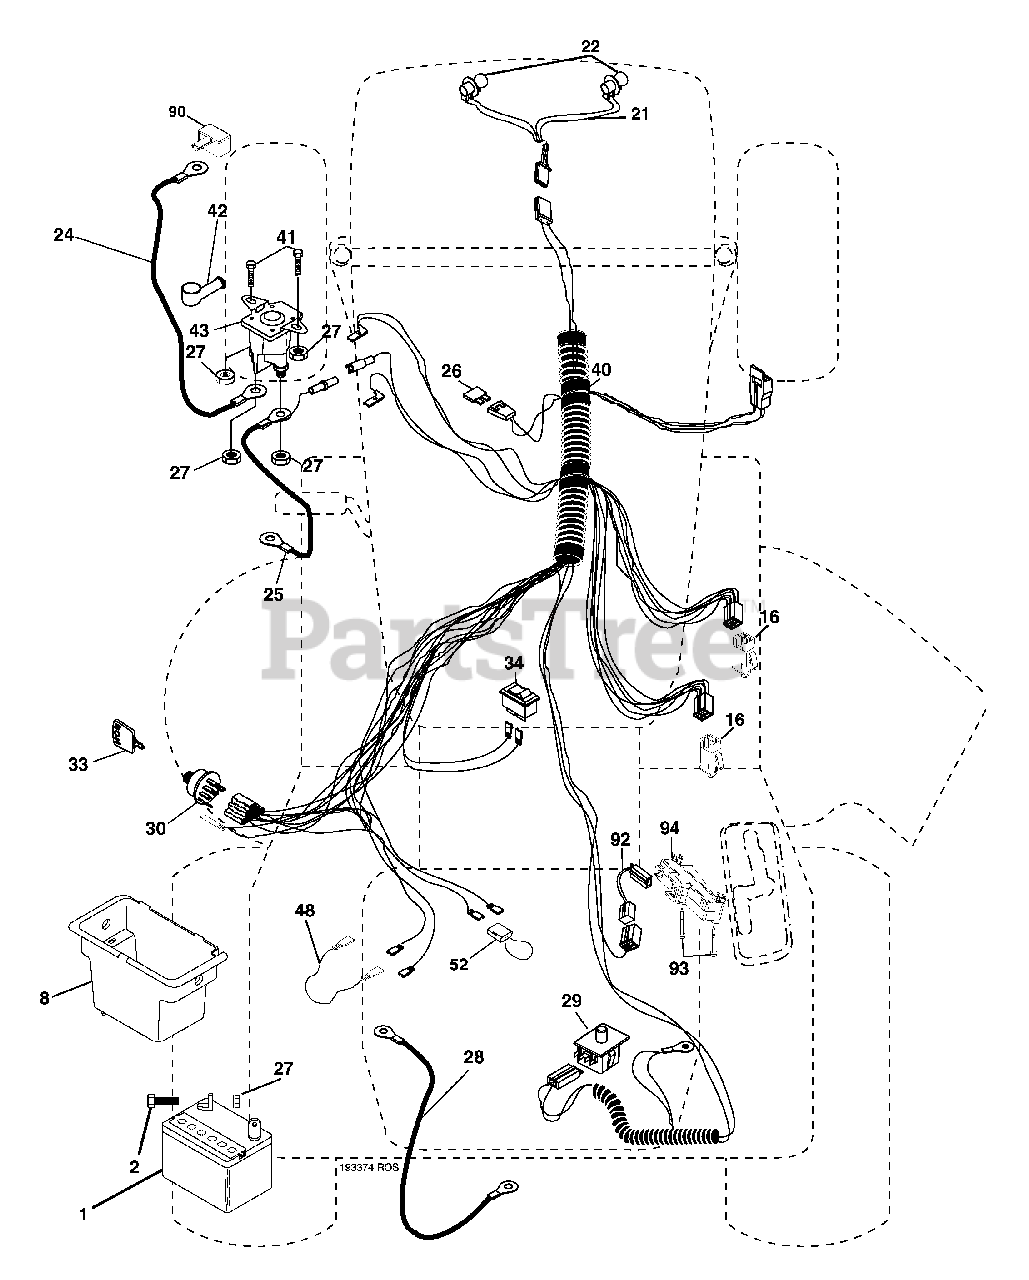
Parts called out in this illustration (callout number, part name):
1	Battery
2	Bolt Hex Hd 1/4-20 unc x 3/4
8	Box Battery
16	Switch Interlock
21	Harness Asm Light W/4152j
22	Bulb Light #1156
24	Cable Battery 6 Ga. 11"red
25	Cable Battery
26	Fuse 20 AMP
27	Nut Keps Hex 1/4-20 unc
28	Cable Ground 6 Ga. 12" Black
29	Switch Seat
30	Switch Ign
33	Key Ign
34	Switch Light/Reset
40	Harness Ign
41	Bolt Blk Fin Hex 1/4-20
42	Cover Terminal Red
43	Solenoid
48	Adapter Ammeter
52	Protection Wire Loop
90	Cover Terminal Battery
92	Harness Pigtail Reverse Switch
93	Screw Plastite 10-14 x 2.0
94	Module Reverse ROS
